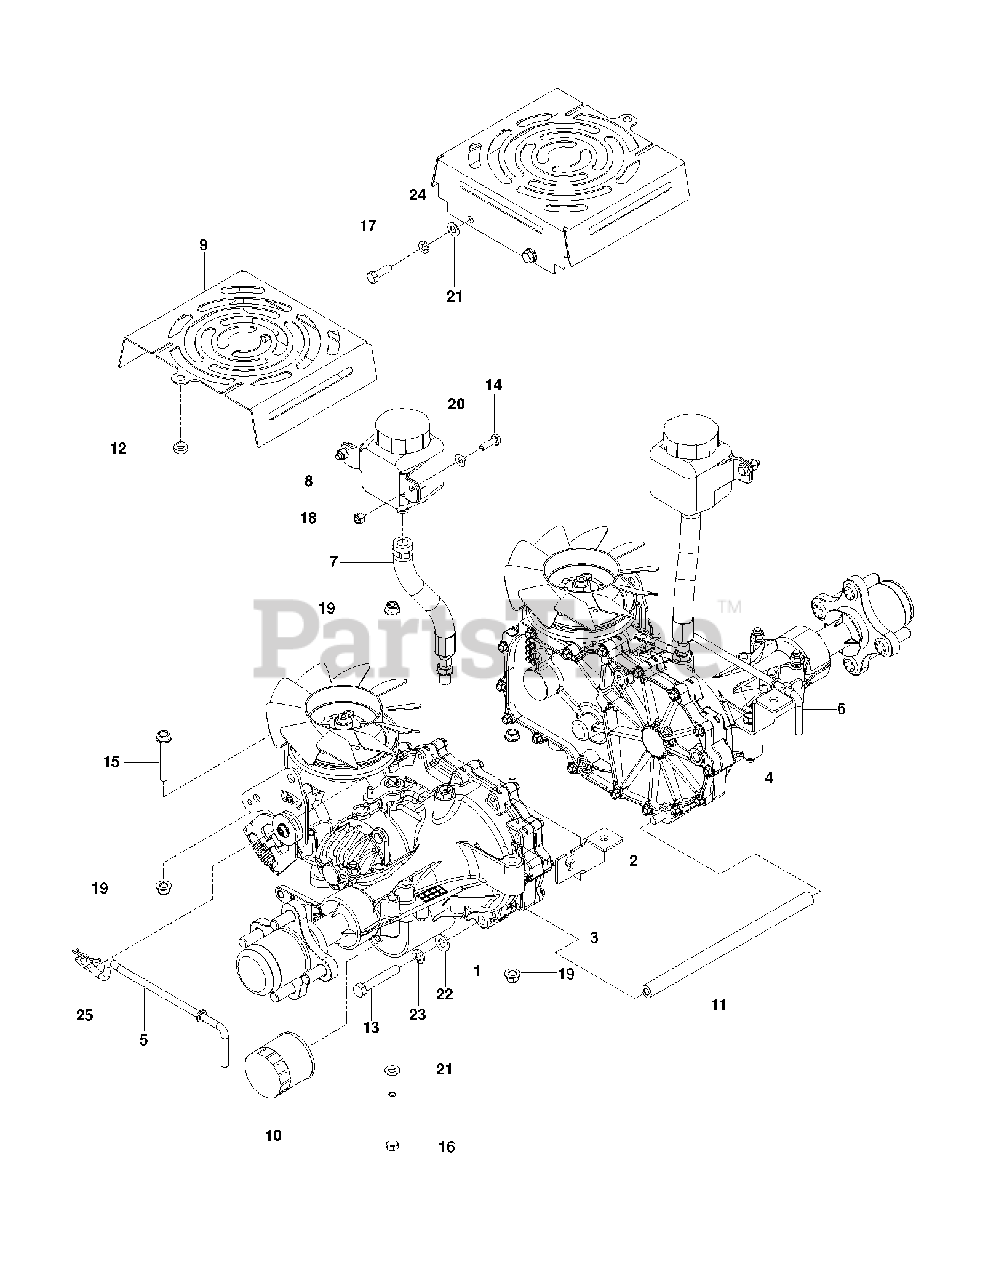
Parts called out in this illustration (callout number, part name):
5	LINKAGE, LEFT BYPASS
6	LINKAGE, RIGHT BYPASS
7	HOSE ASSY, EXPANSION
8	HG_TANK, EXPANSION, 350ML
9	SHIELD, FAN, BLK
10	HG_FILTER, ZT4800
11	TUBE, SPACER, 3400
12	GROMMET, BUMPER
13	HCS 3/8-16X2-1/4 LOC PATCH GR8
14	HCS 1/4-20X7/8 GR5
15	HHFS 5/16-18 X 2.25 GD 5
16	HCS 5/16C X 2-3/4
17	HCS 5/16C X 1
18	NUT 1/4-20 NYLOC
19	5/16-18 NYLOC FLANGE NUT
20	WASHER 1/4 SAE
21	FLAT WASHER 5/16 SAE
22	WASHER 3/8 SAE FLAT
23	SLW 3/8 STD
24	WASHER 5/16 LOCK
25	HAIRPIN #2
